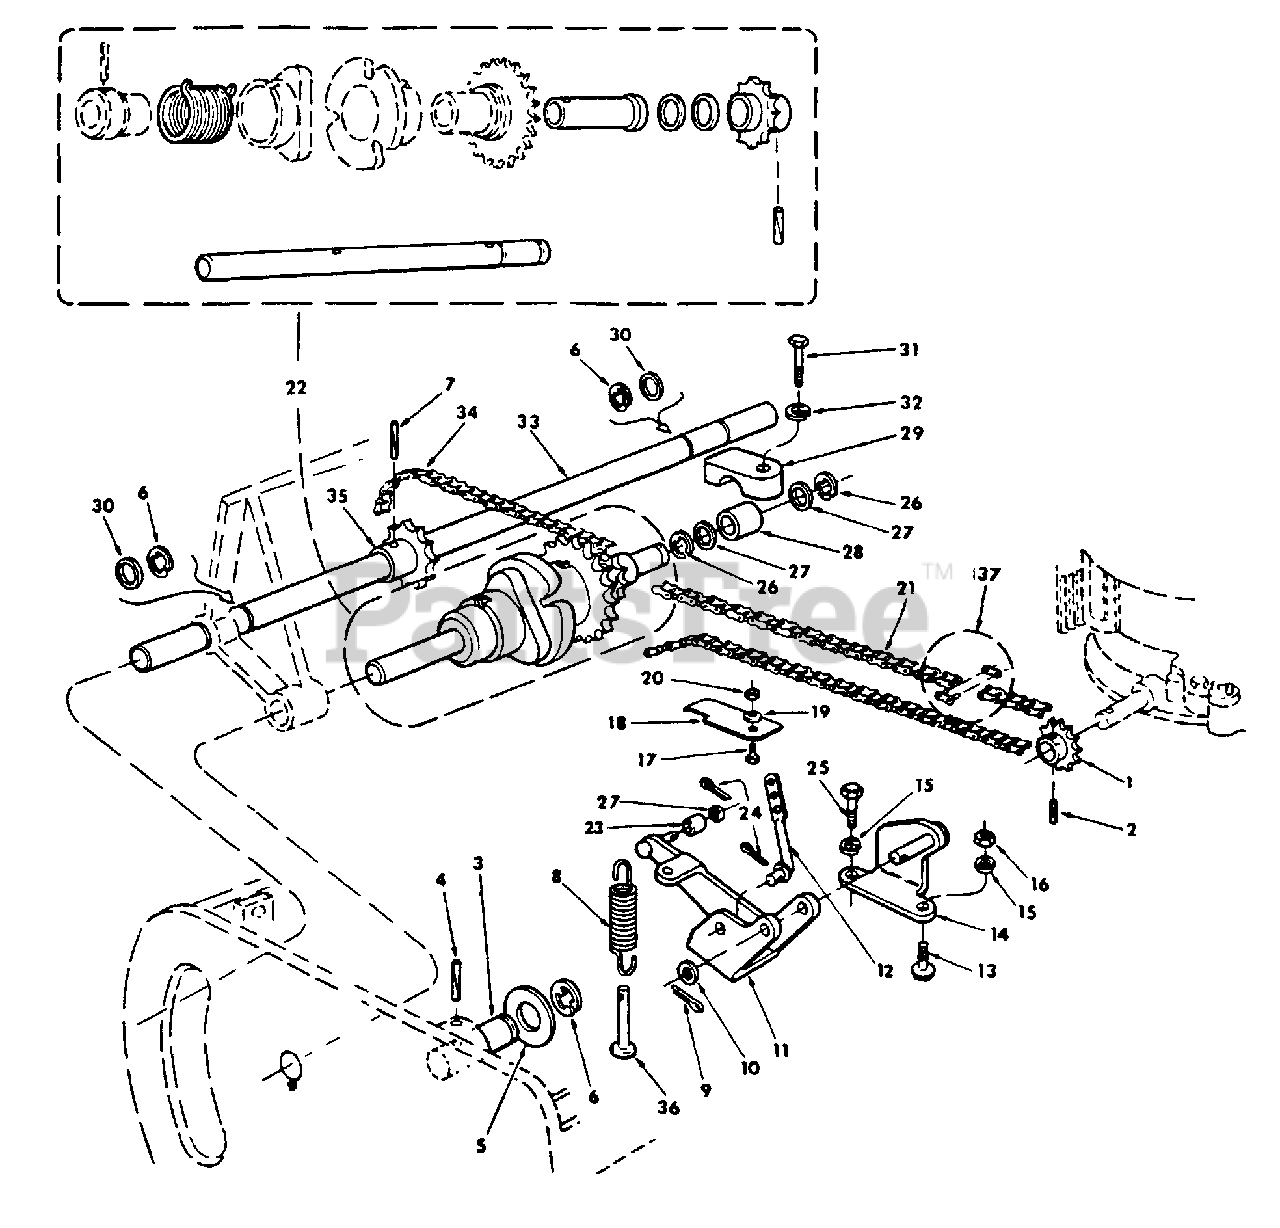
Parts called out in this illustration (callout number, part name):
1	SPROCKET, 12 TOOTH
2	PIN, 3/16 X 3/4 HV SLT SPRING
3	PIN, HANDLE PIVOT RH
4	PIN, 3/16 X 1 HV SLT SPRING
5	WASHER, .500 X 1.250 X .064
6	RING, RETAINING
7	PIN, 3/16 X 1-1/2 HV SLT SPRING
9	PIN, 1/8 X 1 COT.
10	WASHER, .375 X .875 X .064 ZND
11	ARM ASSY, CLUTCH
13	SCREW, 5/16-18 X 1 TRUSS-HD MACH
14	BRACKET ASSY, CLUTCH ARM
15	WASHER, 5/16 REG LOCK
16	NUT, 5/16-18 HEX.
17	SCREW, 10-32 X 1/2 RD-HD mACH
18	KEEPER, CHAIN IDLER
19	WASHER, NO. 10 SPRING LOCK
20	NUT, 10-32 HEX.
21	CHAIN, 97 LINK
22	CLUTCH & SHAFT ASSY
24	PIN, 3/32 X 1/2 COT.
25	SCREW, 5/16-18 X 1 HEX-HD CAP
26	RING, RETAINING -2-
27	WASHER, .188 X .375 X .036
30	WASHER, .594 X 1-1/4 X 1/16
31	SCREW, 1/4-20 X 1 HEX-HD
32	WASHER, 1/4 REG LOCK
33	SHAFT, REAR DRIVE
34	CHAIN, 31 LINK
35	SPROCKET, 18 TOOTH
36	PIN, 5/16 X 1-1/2 STD-HD
37	LINK, MASTER
